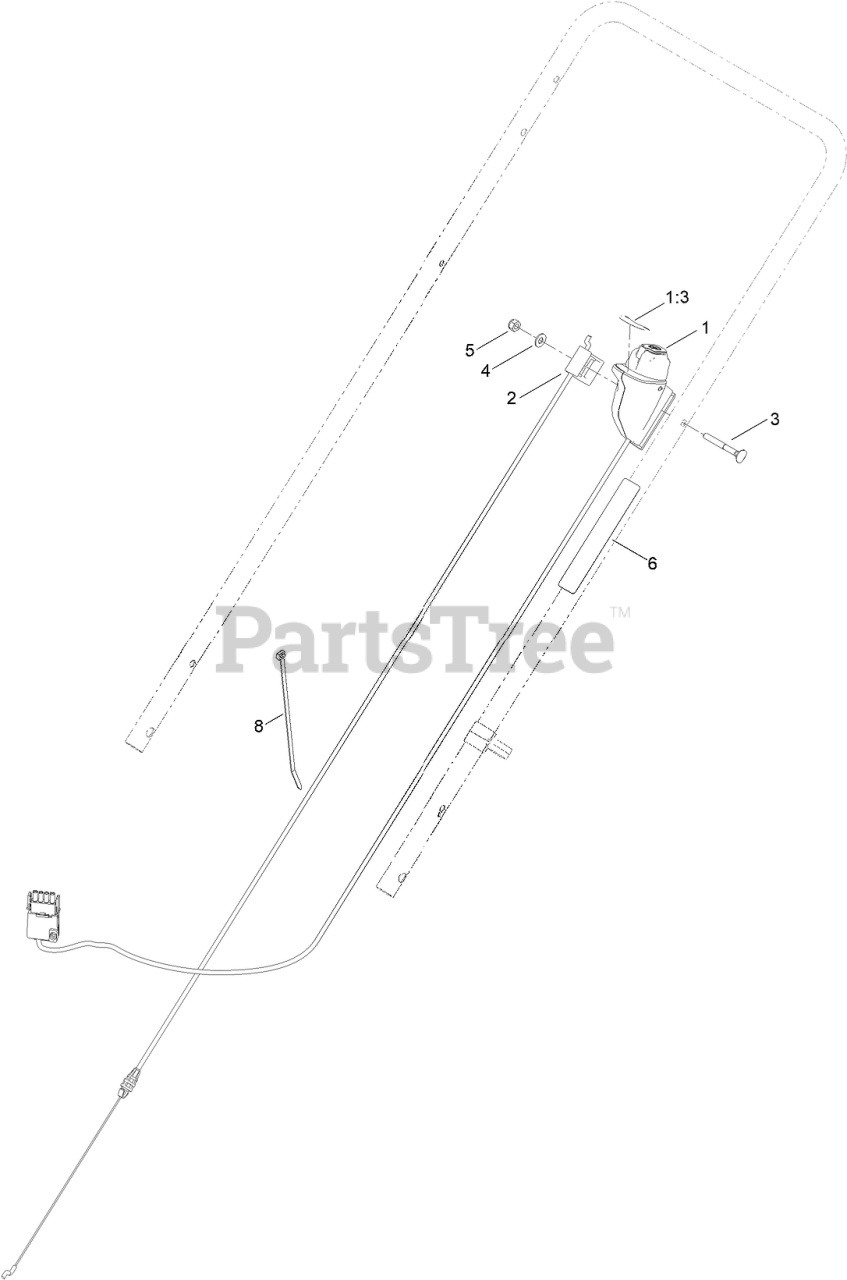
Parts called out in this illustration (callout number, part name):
1	STARTER SWITCH ASM
1:3	STARTER BUTTON SERVICE ASM
2	CABLE - BRAKE
3	SCREW-HANDLE
4	WASHER-FLAT
5	NUT-LOCK, NI
6	DECAL-CONTROLS (60V START)
8	TIE-CABLE
